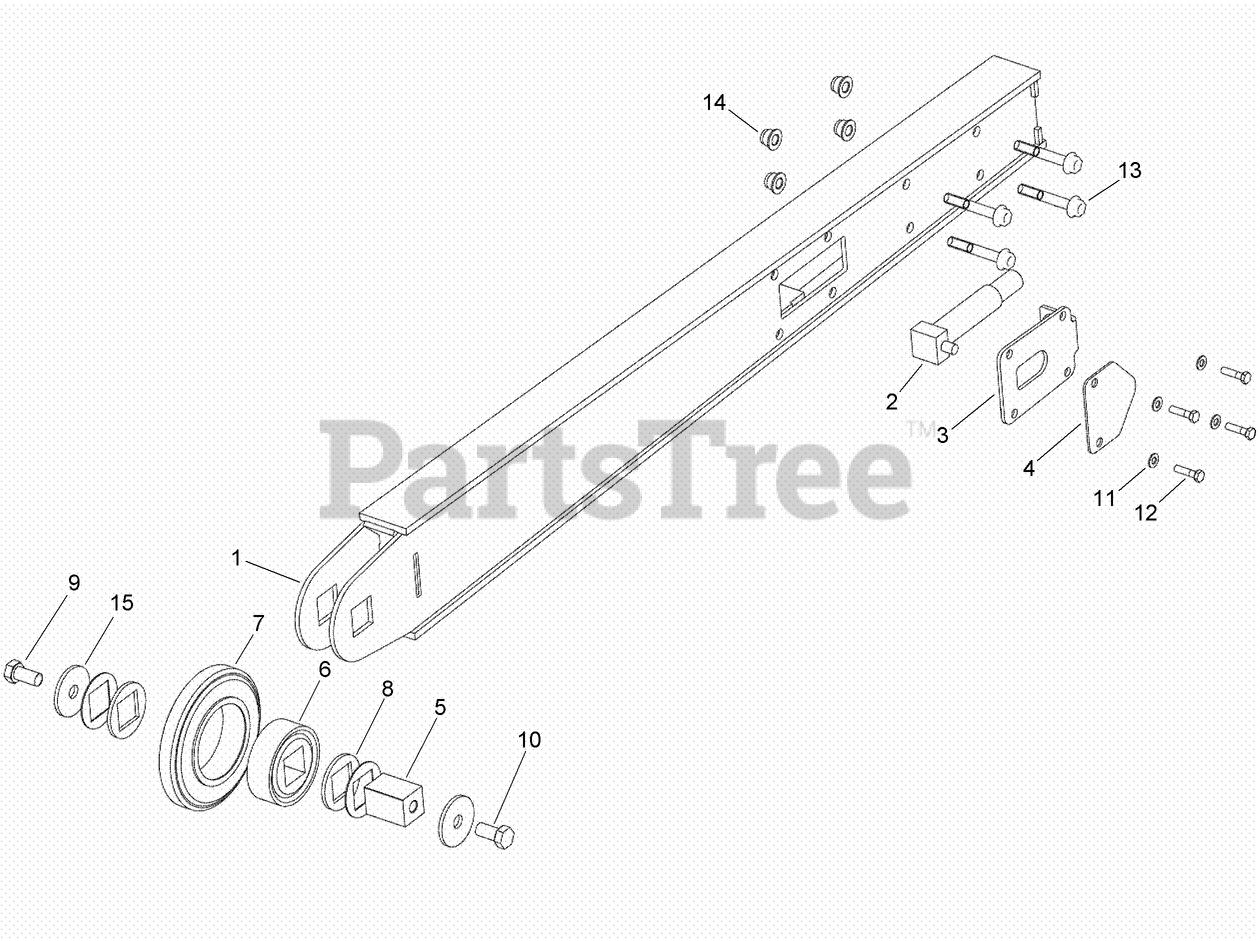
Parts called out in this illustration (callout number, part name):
1	BOOM - 48in Rock
2	PISTON-ADJ
3	PLATE - Piston Keeper
4	PLATE - Cover
5	MOUNT-SHAFT, IDLER
6	BEARING
7	WHEEL-BOOM END, IDLER
8	WASHER
10	BOLT - Hex Hd .625 x 1.25 GR5 ZND
11	WASHER-FLAT
12	BOLT-Hex, 5/16 NC x 1-1/4 inch
13	SCREW-HHF
14	NUT-HHF, LOCK
